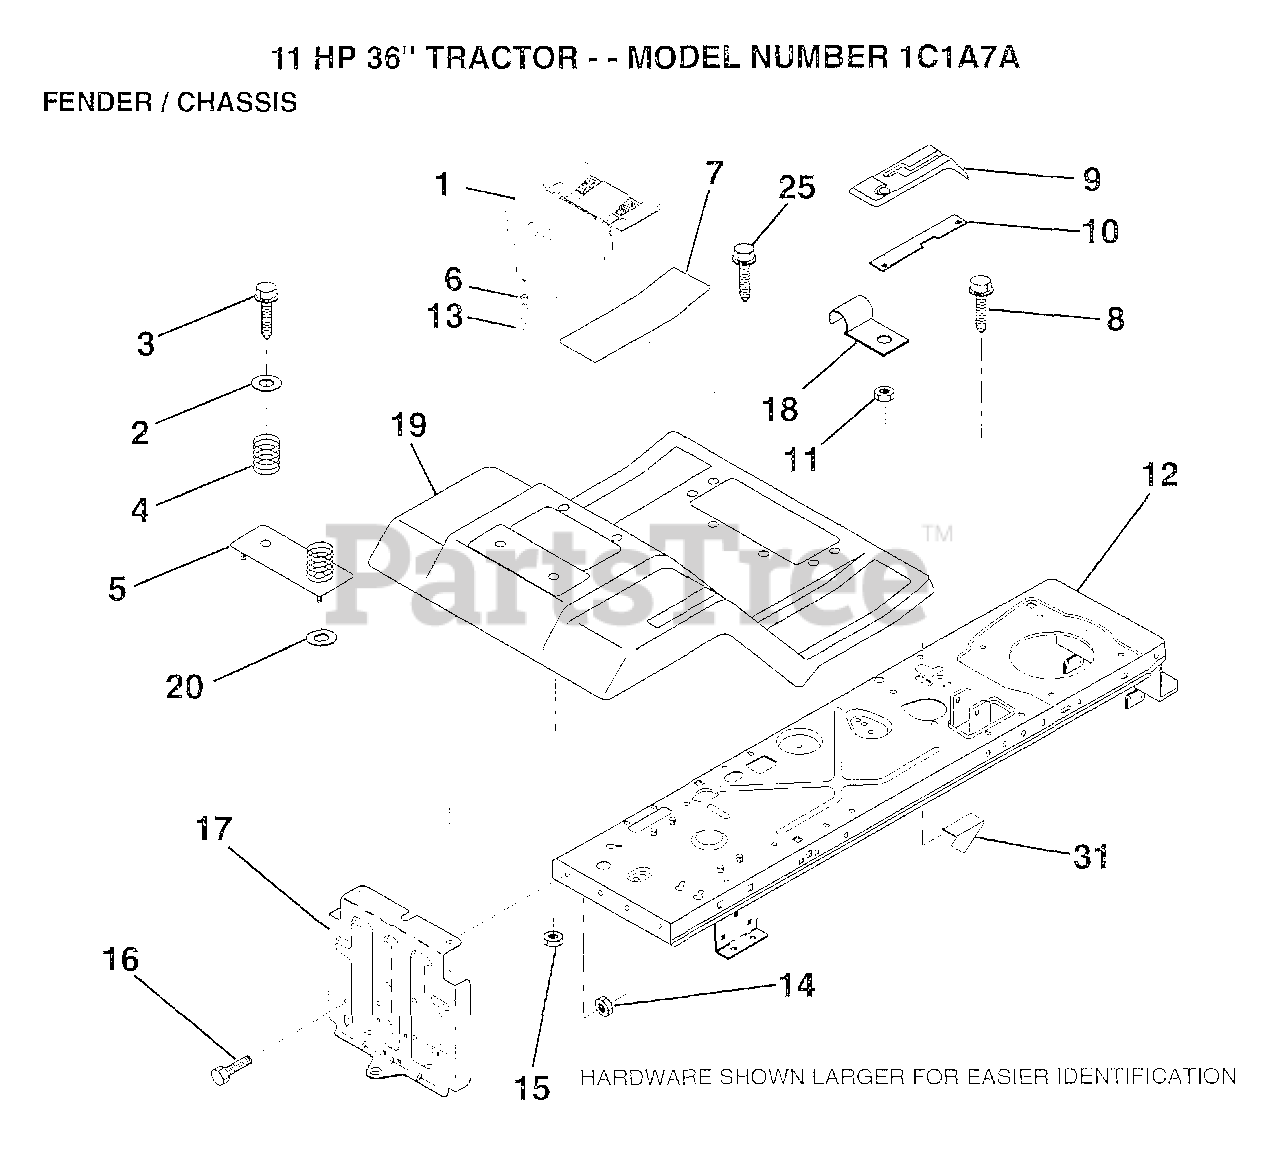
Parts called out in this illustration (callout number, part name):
2	WASHER
3	SCREW
4	SPRING COMPRESSIO
5	BTRY FENDER PLATE
6	HOSE CLAMP T
7	PAD FOOTREST
8	SCREW
9	CONSOLE SHFT 4SP
10	PLATE LOCK SHIFT
11	NUT
13	TUBE T
14	NUT
15	NUT
16	BOLT
17	DRAWBAR ASM LR
18	"CLIP,INSULATOR"
19	FENDER/FOOT MS505
25	SCREW TI
